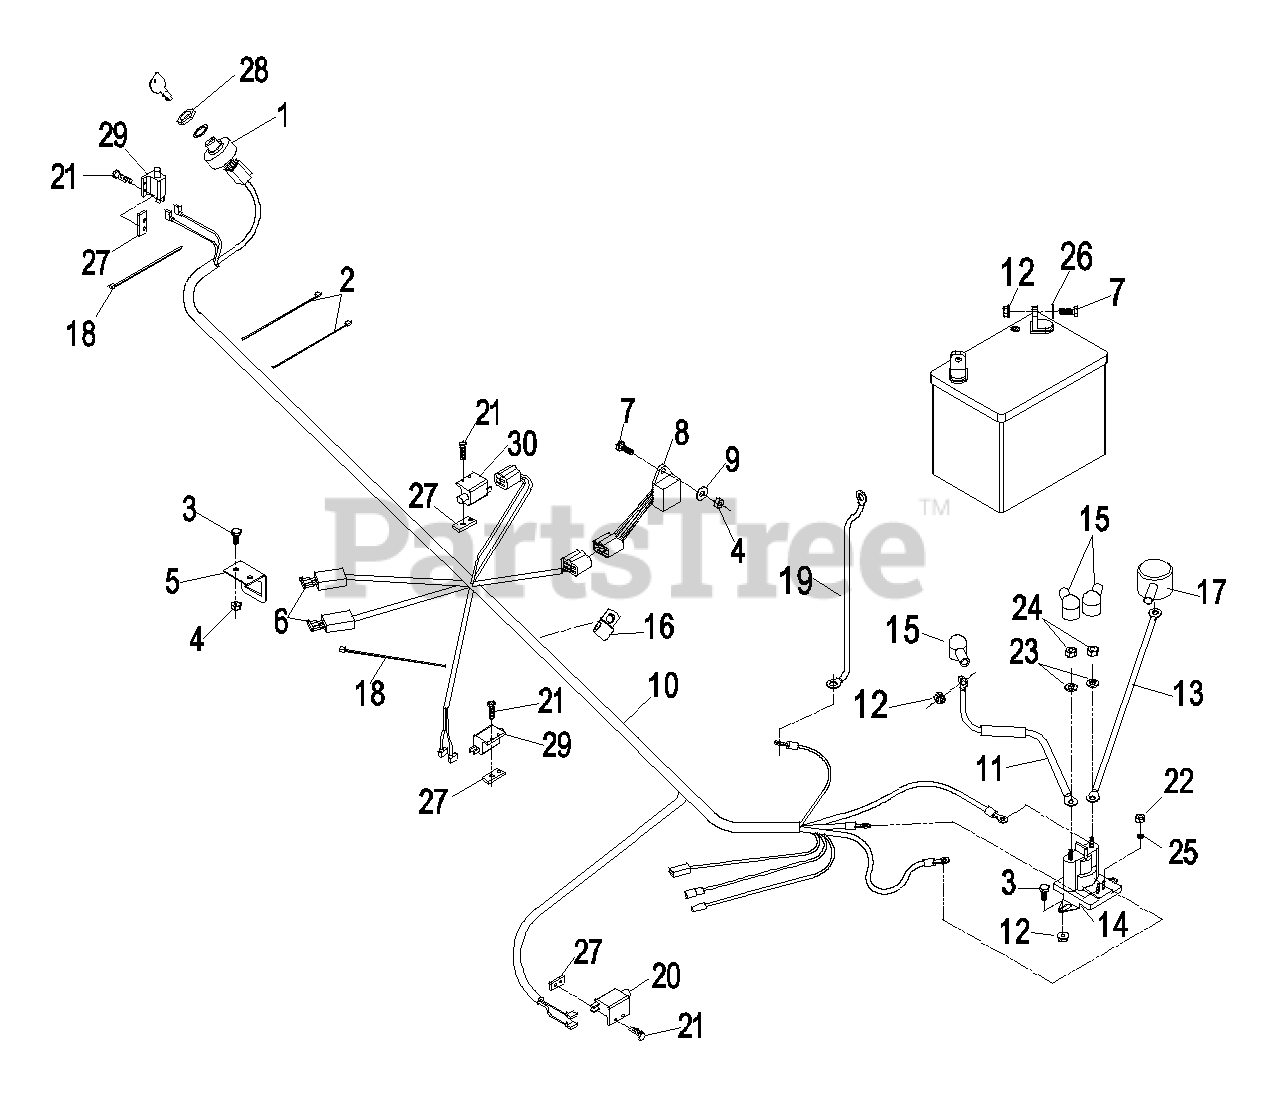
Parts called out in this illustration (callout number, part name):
1	SWITCH,IGNITION
2	TIE-PLASTIC
3	SCREW-HH
4	NUT-LOCK, NI
5	BRACKET,FUSE
6	FUSE-BLADE TYPE, 20 AMP
7	SCREW-HH
8	MODULE-OPC NO TIME DELAY
9	WASHER-FLAT
10	HARNESS,WIRING ELEC ST
11	Cable, Solenoid/Starter +
13	ASM,POSITIVE BATTERY CABLE
14	SWITCH, 12V SOLENOID
15	INSULATOR-SOLENOID
16	CLIP-LOOM
17	INSULATOR-BATTERY
18	TIE-CABLE
19	CABLE-BATTERY, NEGATIVE
20	SWITCH-CLOSED, NORMALLY
21	SCREW-PPH
22	NUT-HEX
23	WASHER-LOCK
24	NUT-JAM
25	WASHER-LOCK
26	WASHER-FLAT
27	PLATE-TAPPED
28	NUT-SWITCH, IGNITION
29	SWITCH-OPEN, NORMALLY
